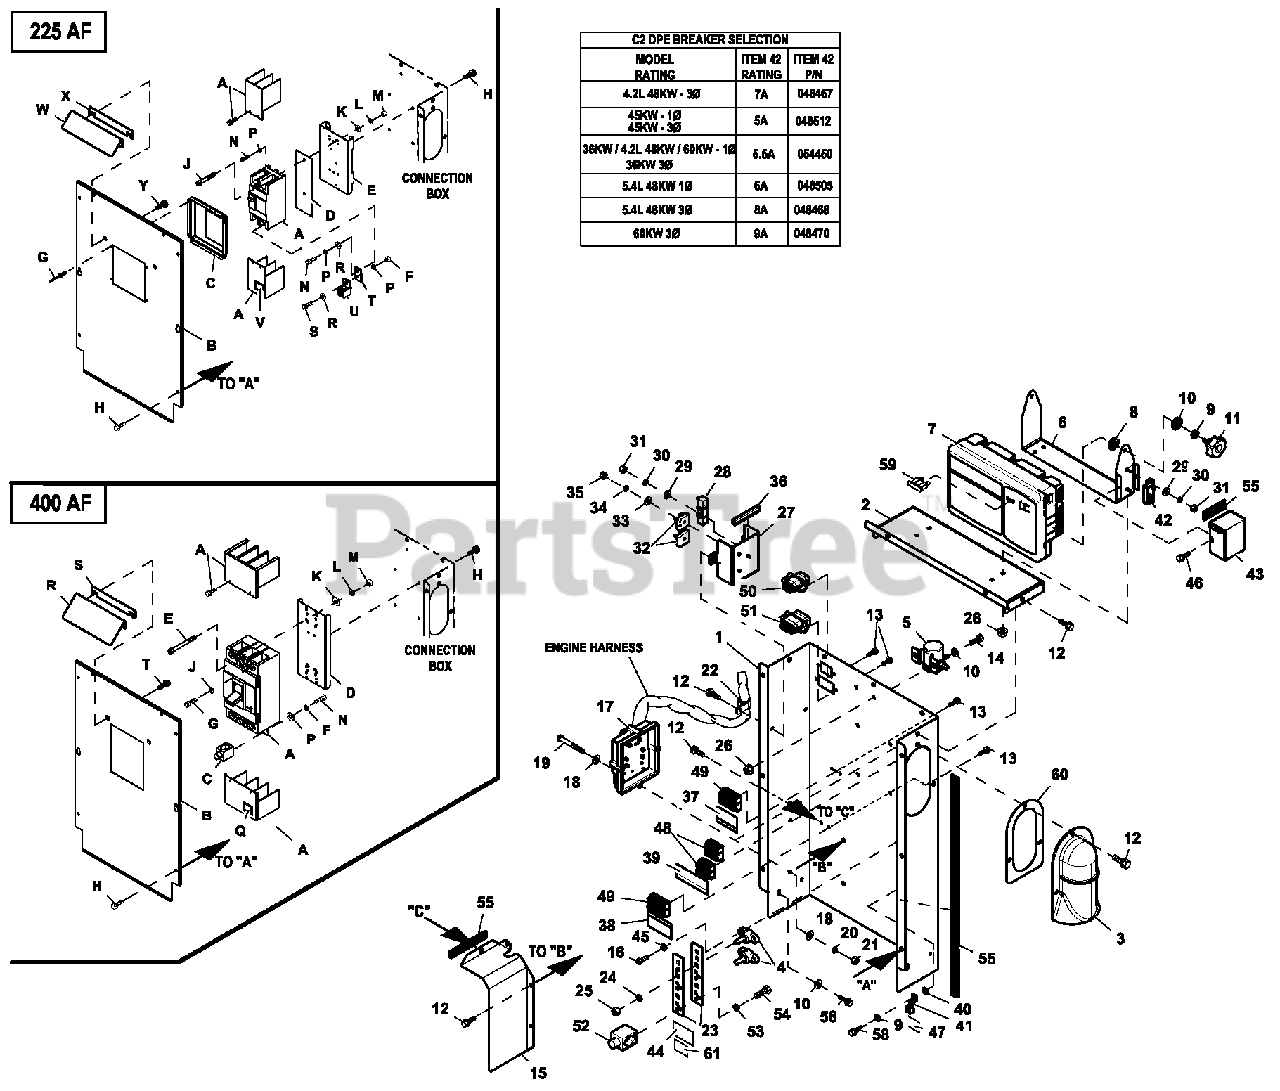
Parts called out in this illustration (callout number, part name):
1	BACK PANEL CONBOX SUPPORT C2
2	TOP PANEL CONBOX SUPPORT C2
3	COVER WIRE ENTRY CONBOX
4	JUNCTION BLOCK 3/8-16
5	RELAY SOLENOID 12VDC PNL MNT
6	BRACKET GIMBAL CONTROL PNL RAW
7	ASSY CTRL PROGRAMMED
8	WASHER FLAT NYLON 0.257 X 0.625
9	WASHER LOCK M6-1/4
10	WASHER FLAT 1/4-M6 ZINC
11	KNOB M6-1.0 CONTROL PANEL
12	SCREW HWHT M6-1 X 16 N WA Z/JS
13	SCREW HHSP #10 X 3/8 HI-LOW
14	SCREW HHC M6-1.0 X 20 C8.8
15	SHIELD HIGH/LOW C2 RAW
16	SCREW PHTT M4-0.7 X 12 ZP
17	ASSY PROG 2010 IGN MOD 6 CYL
18	WASHER FLAT #10 ZINC
19	SCREW PPHM # 1 0 -3 2X 2
20	WASHER LOCK #10
21	NUT HEX #10-32 STEEL
22	CLAMP STL/VNL 1.06 X .406 Z
23	NEUTRAL BLOCK 390/200-400A
24	WASHER LOCK 3/8
25	NUT HEX 3/8-16 STEEL
26	NUT FLANGE M6-1.0 NYLOK
27	COVER VOLTAGE SHIELD
28	RES WW 15R 5% 25W QK CONN
29	WASHER FLAT M3
30	WASHER LOCK M3
31	NUT HEX M3-0.5 G8 CLEAR ZINC
32	DIODE BRIDGE 1P 35A 1000V
33	WASHER FLAT M5
34	WASHER LOCK M5
35	NUT HEX M5-0.8 G8 CLEAR ZINC
36	TRIM VINYL BLACK 1/8GP (3"LG)
37	DECAL CUSTOMER POWER CONNECT
38	DECAL CUSTOMER CONTROL CONNECT
39	DECAL CONBOX TB1 CONNECTIONS
40	WASHER LOCK EXT 1/4 STL
41	LUG SLDLSS #2-#8 X 17/64 CU
42	CIRCUIT BREAKER
43	COVER DPE BREAKER NEXUS RAW
44	DECAL NEUTRAL
45	WASHER LOCK#8-M4
46	SCREW HHTT M4-0.7 X 8 ZP
47	DECAL GROUND LUG
48	TERM BLOCK 3P UL 12-20AWG
49	TERM BLOCK 4P UL 12-20AWG
50	MX150L SLRRMNT 22-18 8P W/O GA
51	MX150L SLRRMNT 22-18 12P W/OGA
52	LUG SLDLSS 600/250-1/0X1/4-28
53	WASHER LOCK 1/4-M6 SS
54	SCREW HHC 1/4-28 X 3/4 G5
55	TAPE ELEC 1/2 FOAM (69"LG)
58	SCREW HHTT M6-1.0 X 16 ZYC
59	FUSE ATO TYPE 7.5AMP (BROWN)
60	GASKET WIRE ENTRY COVER
61	DECAL CAUTION ELEC SHOCK SM
A	CB 175A 2 POLE 240V 225AF
B	COVER CB C2 CPL
C	COVER CB DISH 2P G 225AF
D	INSULATOR CB 2P 225AF
E	STANDOFF CB BOX CONBOX
F	NUT HEX M8-1.25 G8 CLEAR ZINC
G	RIVET POP .125 X .275 SS
H	SCREW HWHT M6-1 X 16 N WA Z/JS
J	SCREW RHM #8-3 2X3 -1 /4
K	WASHER FLAT #8 ZINC
L	WASHER LOCK#8-M4
M	NUT HEX #8-32 STEEL
N	SCREW SHC M8-1.25 X 20 G8
P	WASHER LOCK M8-5/16
R	WASHER FLAT 5/16-M8 ZINC
S	SCREW SHC M8-1.25 X 25 C12.9
T	BUS BAR 200A LUG ADAPTOR
U	LUG SLDLSS 300 MCM-6 AL/CU
V	DECAL TERMINAL SHOCK HZD BI
W	SHIELD-SM CIRCUIT BREAKER
X	GASKET-CB SHIELD C2
Y	SCREW HWHTF M6-1.0 X 1 6
A	CB 0250A 3P 480V G 400AF
B	COVER CB 400AF C2 CONBOX
C	LUG SLDLSS 600/250-1/0X1/4-28
D	STANDOFF CB MOUNT CONBOX
E	SCREW RHM 1 0 -3 2X 4
F	WASHER LOCK M6-1/4
G	SCREW SHC M10-1.5 X 25 C12.9
J	WASHER LOCKM10
K	WASHER FLAT #10 ZINC
L	WASHER LOCK #10
M	NUT HEX #10-32 STEEL
N	SCREW HHC 1/4-28 X 1/2 G5
P	WASHER FLAT 1/4-M6 ZINC
Q	DECAL TERMINAL SHOCK HZD BI
R	SHIELD-LGE CIRCUIT BREAKER
S	GASKET-CB SHIELD C2
T	SCREW HWHTF M6-1.0 X 1 6
